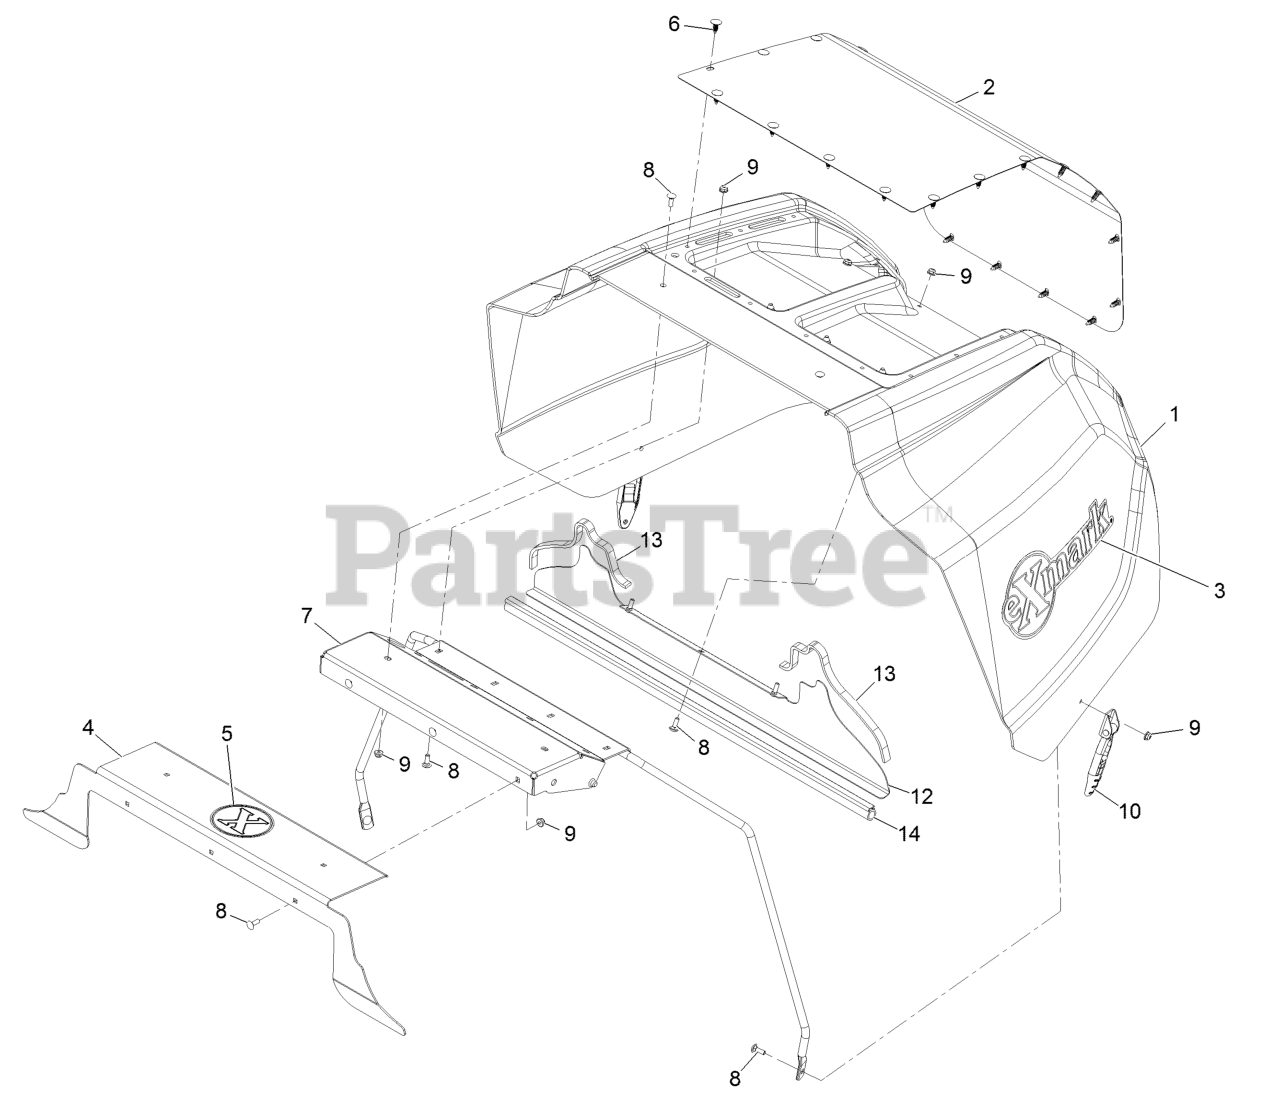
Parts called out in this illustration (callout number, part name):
1	Hood
2	Screen-Intake
3	Decal-Exmark
4	Hood-Block Off
5	Decal-X-Logo
6	Plug-Plastic
7	Support-Hood
8	Bolt-Carriage 1/4-20 X 3/4
9	Nut-Nyloc 1/4-20 Flg
10	Latch-Rubber
12	Plate-Seal
13	Seal-Foam
14	Seal-Bulb
